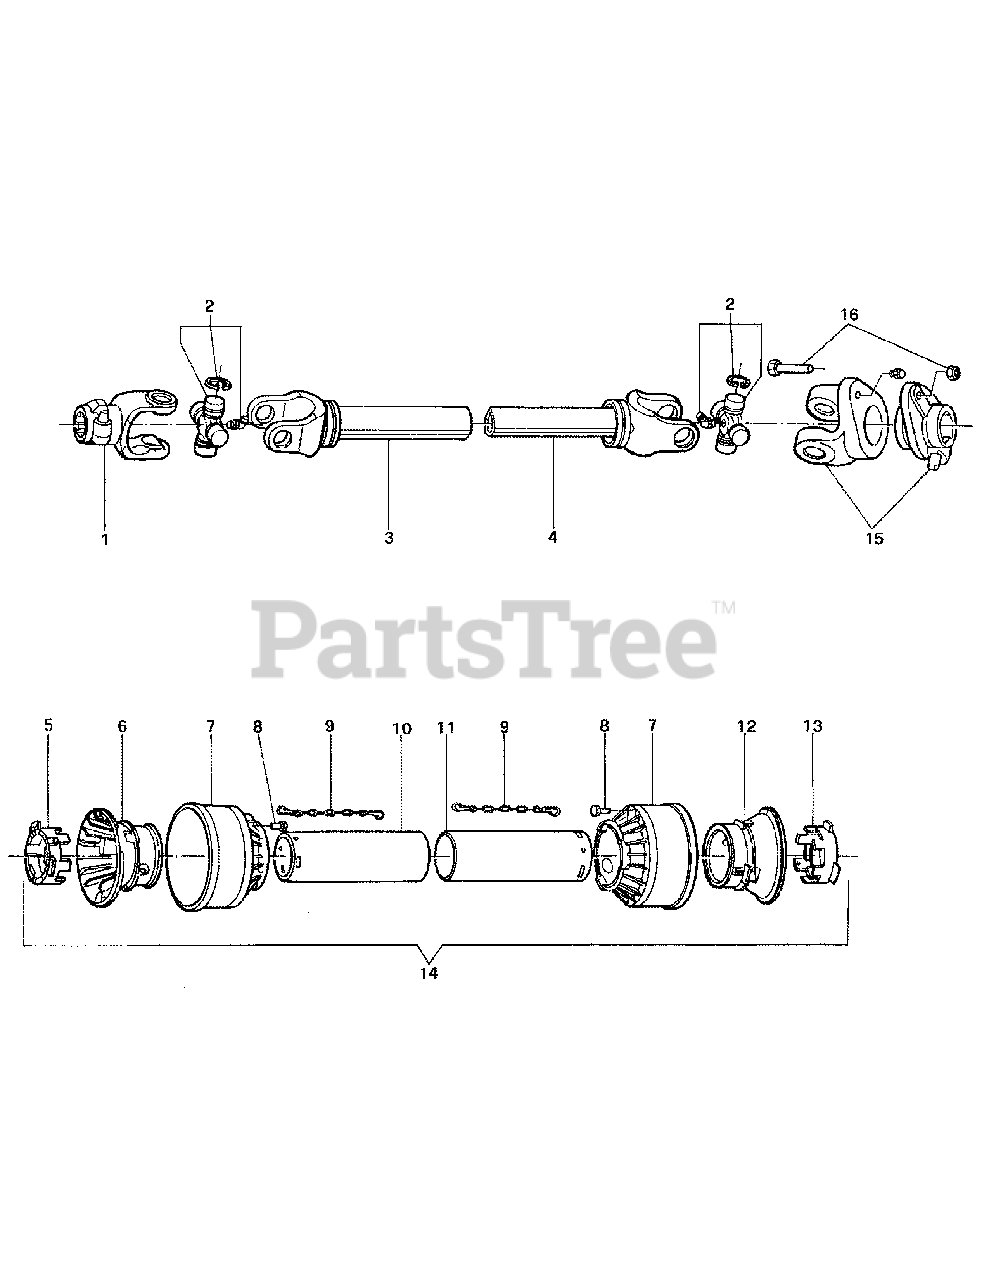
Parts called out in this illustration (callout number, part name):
1	PTO Yoke
2	Cross & Bearing
3	Outer tube for V2
4	Inner tube for V2
5	Outer locking ring (below #1F048001)
6	Outer tube rigid cone (below #1F048001)
7	Outer cone (below #1F048001)
8	Pin (below #1F048001)
9	Chain
10	Female tube shield
11	Male tube shield
12	Inner tube rigid cone (below #1F048001)
13	Inner locking ring (below #1F048001)
14	Complete shielding (below #1F048001)
15	Shearpin coupler for V2
